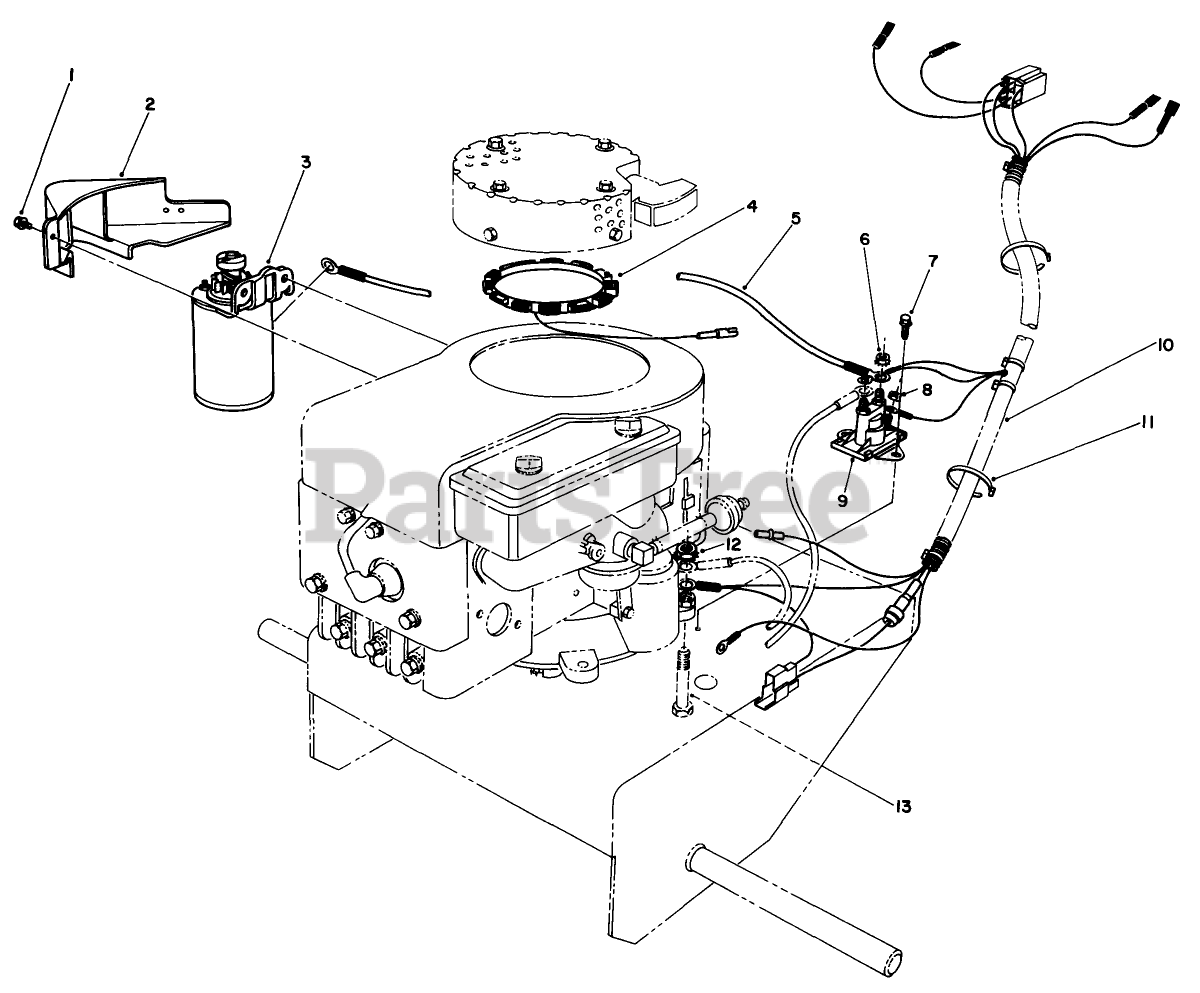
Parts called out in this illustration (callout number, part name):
1	Decal-Electric Start Panel
2	KEY-IGNITION
3	NUT-HH
4	WASHER-TOOTH, INTERNAL
5	Ignition Switch (Incl. Ref. #2-4)
6	SCREW-HWH
7	RECTIFIER-BRIDGE
8	PANEL-BOTTOM
9	NUT-LOCK, NI
10	SCREW-HWHTF
